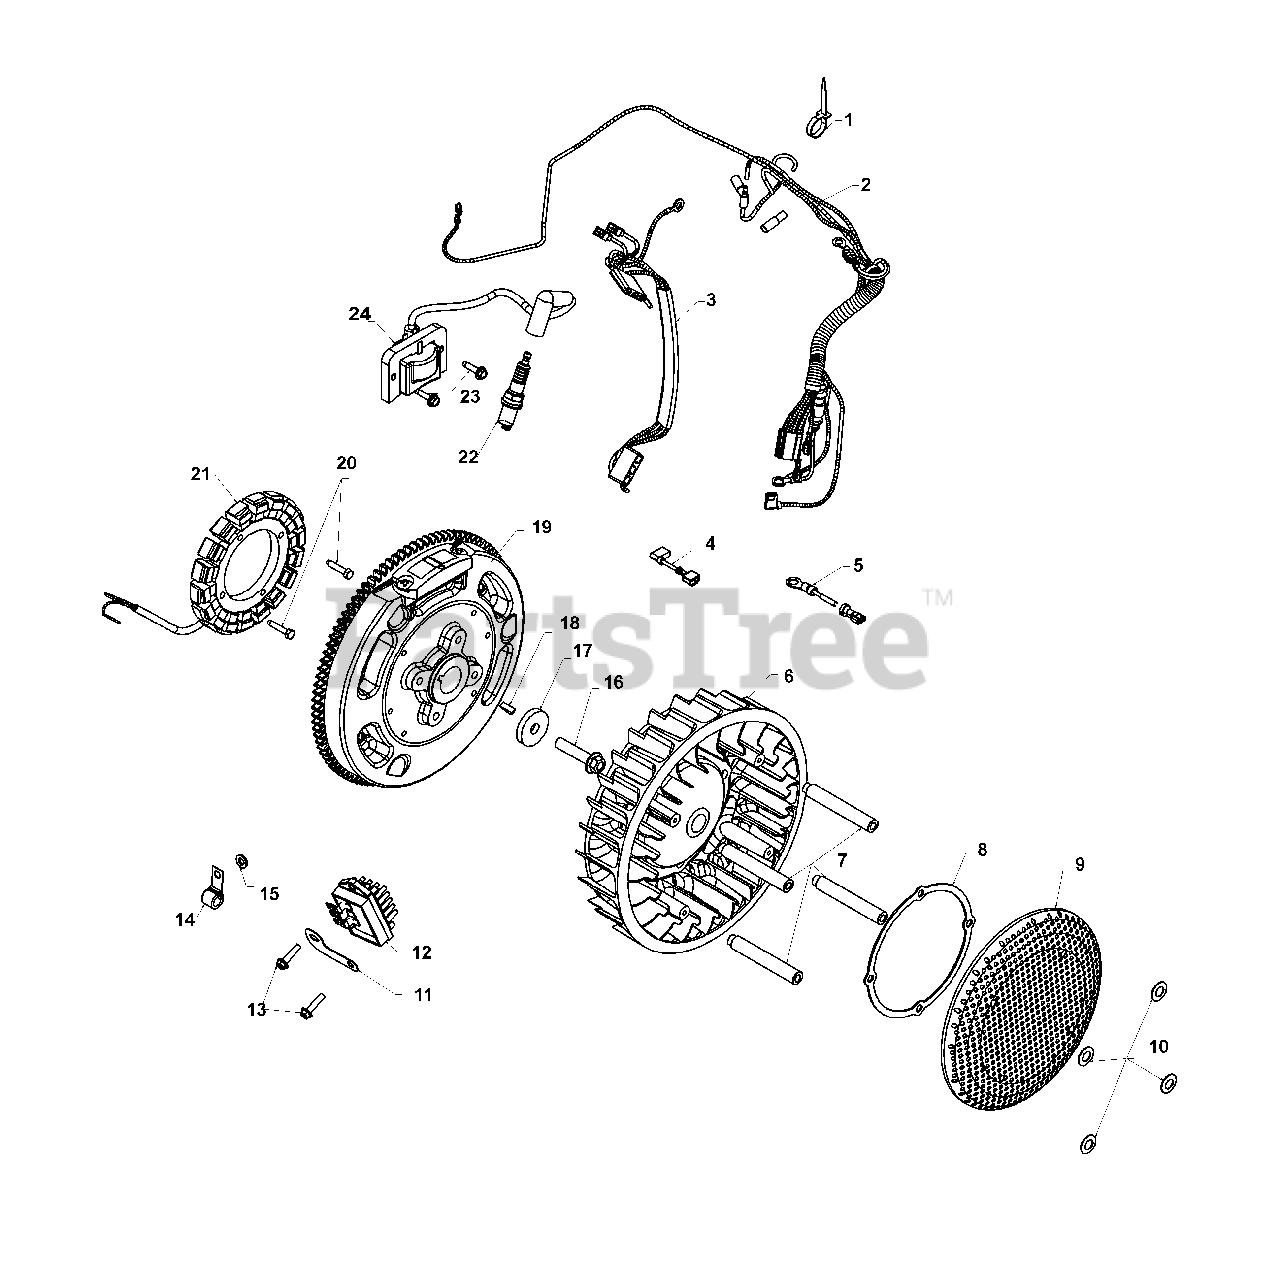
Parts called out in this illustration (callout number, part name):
2	Wiring Harness
3	DSAI Wiring Harness
4	Oil Sentry Lead
8	Support Ring
10	Spring Washer, 10 mm
11	Ground Strap Bracket
12	Rectifier Regulator
13	Hi-Lo Hex Flange Screw
14	Cable Clip
15	Flat Washer, 1/4
16	Flange Screw, M10 x 1.5 x 45
17	Flat Washer, 13/32
18	Key, 3/16 x 5/8
20	Screw, M5 x 0.8 x 25
21	15 Amp Stator Kit
23	Flange Screw, M5 x 0.8 x 20
24	Spark Module (DSAI) Assembly
